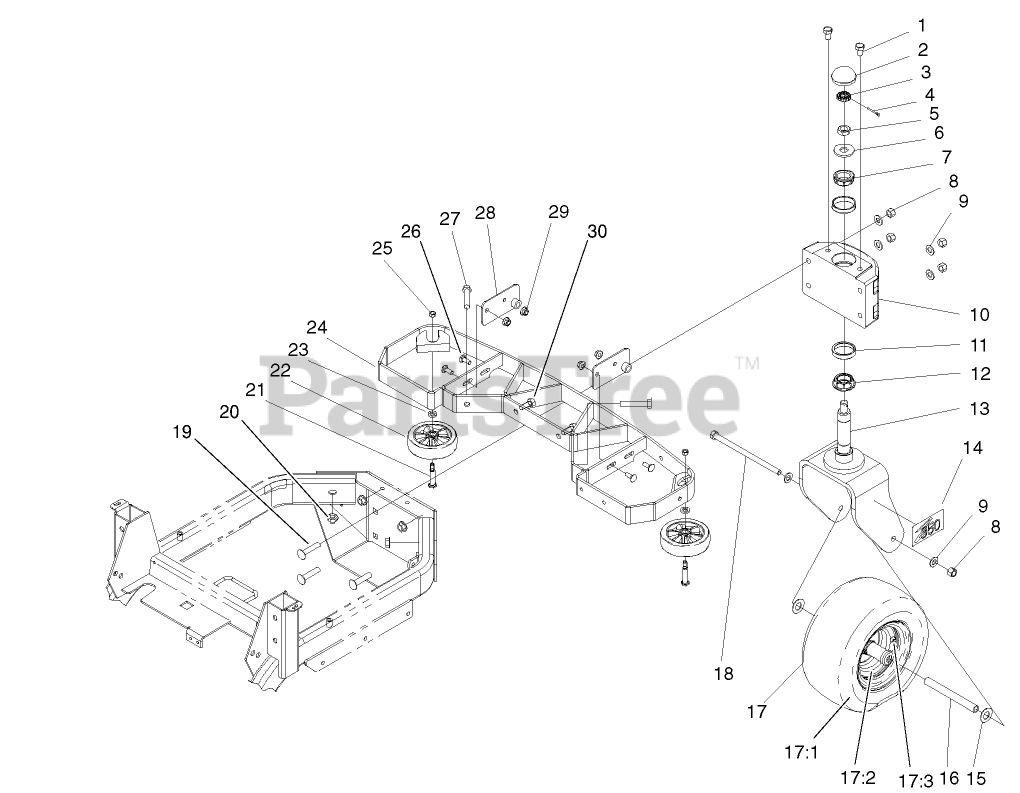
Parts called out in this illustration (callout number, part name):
1	SCREW-HH
2	DUSTCAP
3	NUT-LOCK, RETAINER
4	PIN-COTTER
5	NUT-JAM
6	WASHER-FLAT
7	BEARING-ROLLER, CONE
8	NUT-LOCK, NI
9	WASHER-FLAT
10	HOUSING - SPINDLE
11	CUP-BEARING, ROLLER
12	BEARING-CONE
13	CASTER FORK ASM
14	DECAL - Z350
15	WASHER-FLAT
16	TUBE-SPACER, CASTOR
17	Tire And Wheel ASM
17:2	WHEEL ASM
17:3	STEM-VALVE
18	SCREW-HH
19	SCREW-CARR
20	NUT-HF
21	BOLT-SHOULDER
22	WHEEL ASM
23	Spacer
24	BUMPER ASM
25	NUT-LOCK, SIDE
26	BOLT-CARR
27	SCREW-HH
28	PIVOT ASM
29	NUT-HF
30	SCREW-HH
